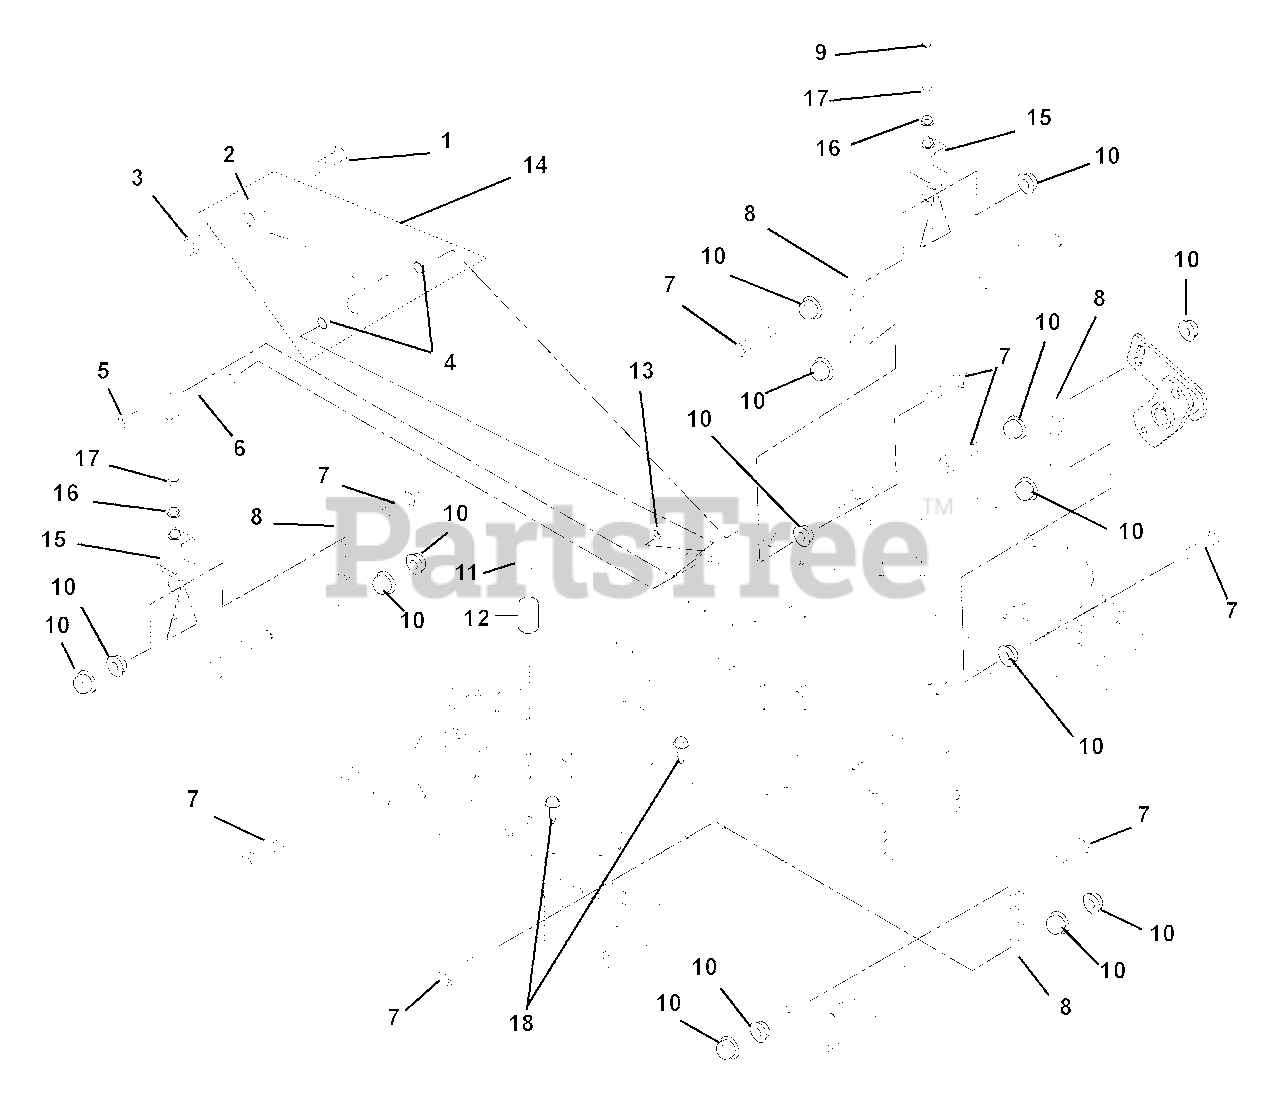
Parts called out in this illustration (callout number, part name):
1	Bolt, Hex .875-9 x 2.75 Grade 5
2	Mower Mounting Arm Weldment
3	Nut, Locking-Center .875-9
4	Bearing, .75 x .875 x 1.00
5	Bolt, Hex .38-16 x .75 Grade 5
6	Weldment, Mower Mounting Pin
7	Bolt, Hex M12-1.75 x 50 Grade 5
8	Chain, Link
9	Cap, Vinyl .50 ID x 1.50LG x .055
10	Nut, Spin Lock-Flange M12-1.75
11	Bumper, Rubber
12	Standoff, .38-16 x .50 Self Tapping
13	Nut, .38-16 Nyloc Flange
14	Assembly, Mower Mounting Arm
15	Bracket, Deck Leveling
16	Nut, Jam .312-18
17	Bolt, Full Thread Hex .312-18 x 2.00
18	Screw, Tapping Hex Washer Head Thread .38-16 x .50
